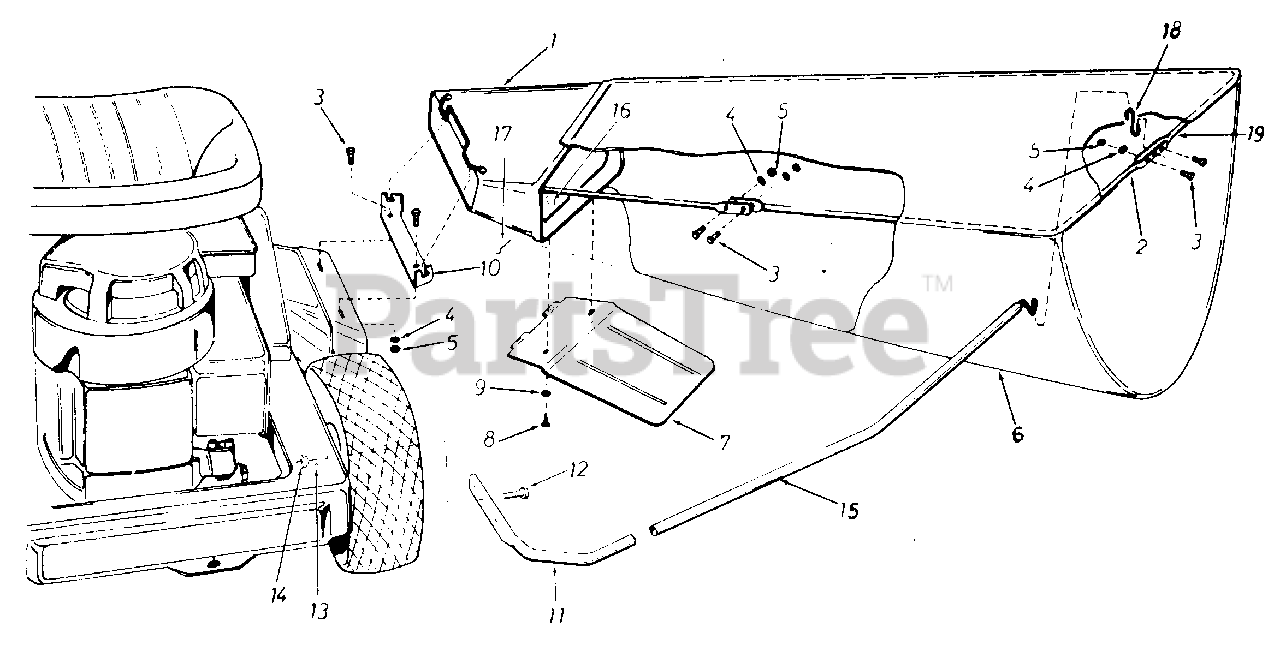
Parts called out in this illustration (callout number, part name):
1	Shroud Assy.
2	Rear Supporting Rd.-L.H.
3	Hex Scr. 1/4-20 x .75" Lg.*
4	L-Wash. 1/4" Scr.*
5	Hex Nut 1/4-20 Thd.*
7	Skid Plate
8	Hex Scr. Wash. HD. #10 x .50" lg.*
9	L-Wash. #10 Scr.*
10	Attachment Bracket
11	Lower Support Tube
12	Hex Scr. 3/8-16 x .75" Lg.*
13	L-Wash. 3/8" Scr.*
14	Hex Nut 3/8-16 Thd.*
15	Upper Support Tube Assy.
16	Sq Nut #10-24 Thd.*
17	Mach. Scr. Rd. Hd. Slot #10-24 x .50" Lg.*
18	Hook-Bag Support
19	Rear Supporting Rod. R.H.
